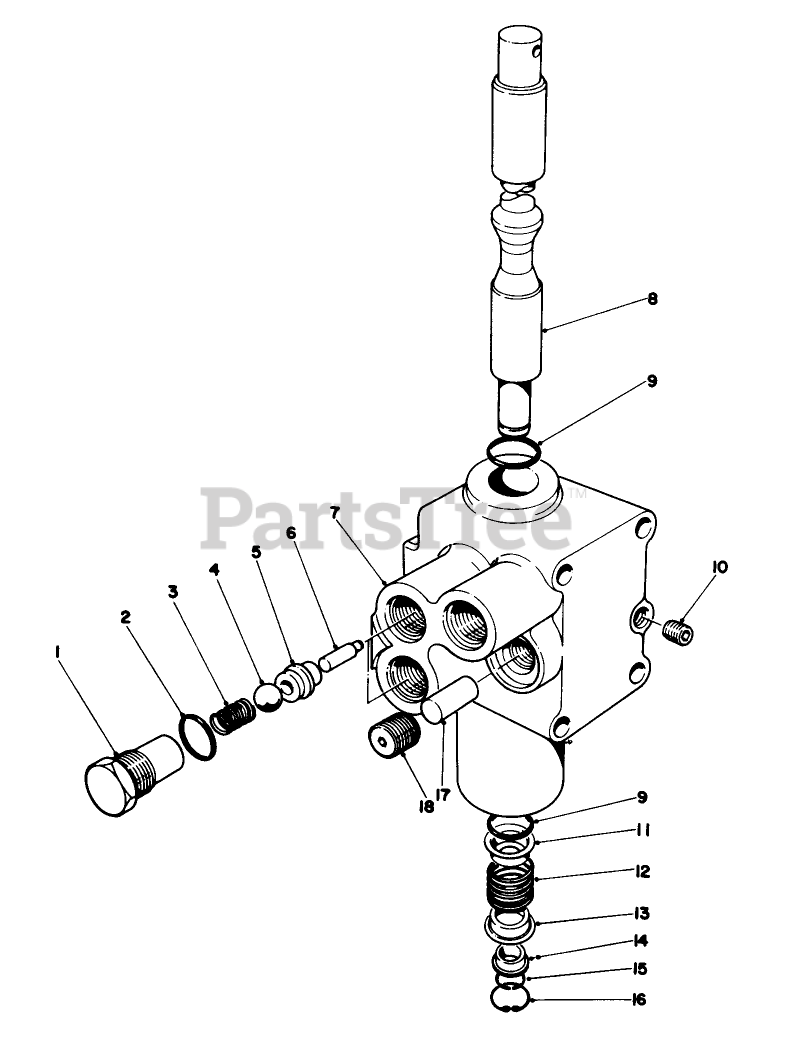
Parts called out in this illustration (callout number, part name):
2	O-RING
3	SPRING
5	SEAT-VALVE
7	Body
8	SPOOL
9	O-RING
11	RETAINER
12	SPRING
13	RETAINER
14	SPACER
15	RING-SNAP
16	RING-SNAP
